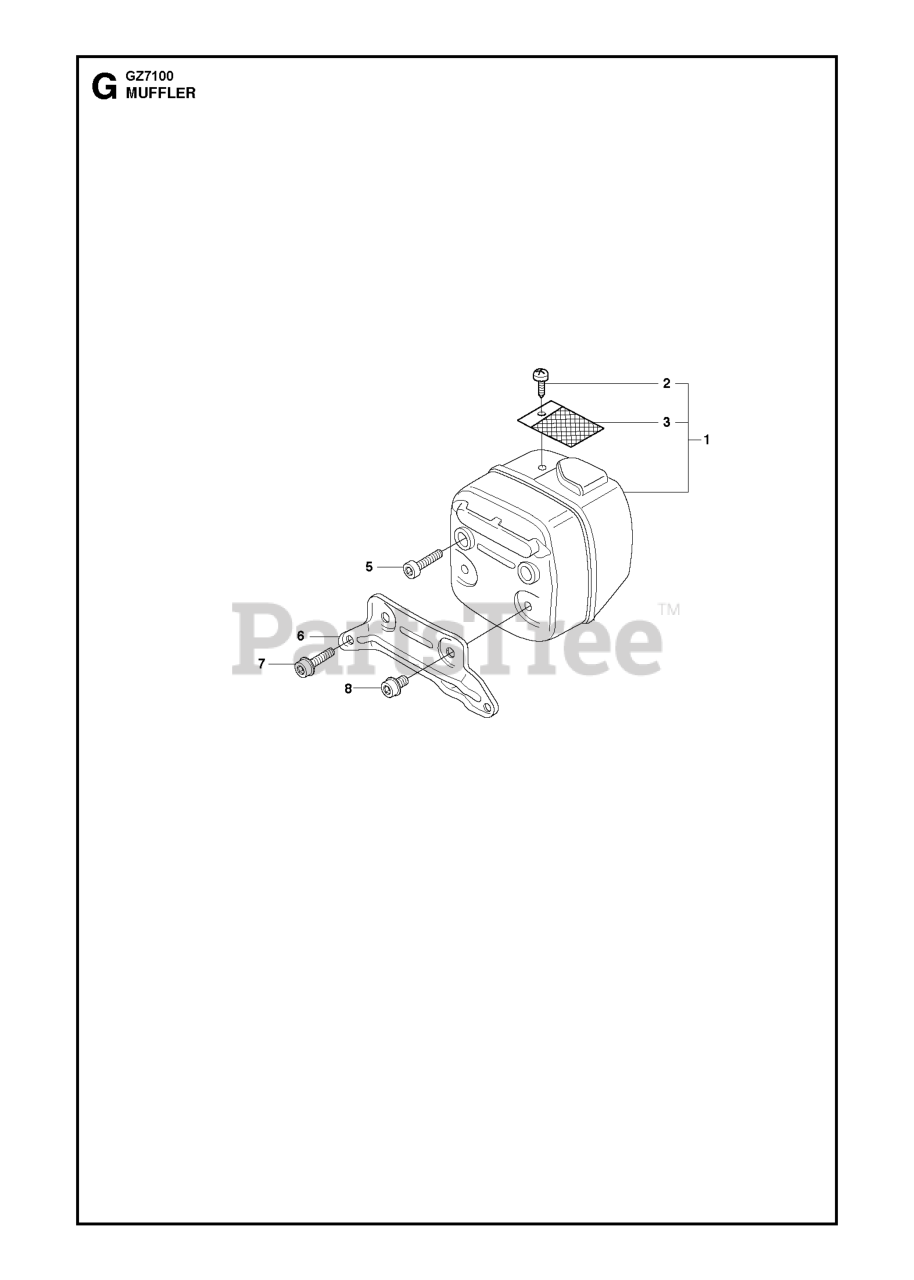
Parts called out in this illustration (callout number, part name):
1	MUFFLER
2	SCREW
3	SCREEN
5	SCREW ITXSCM M6X20 T27 12.9 T
8	SCREW ITXSCFM M5X8 T27 10.9 Z
